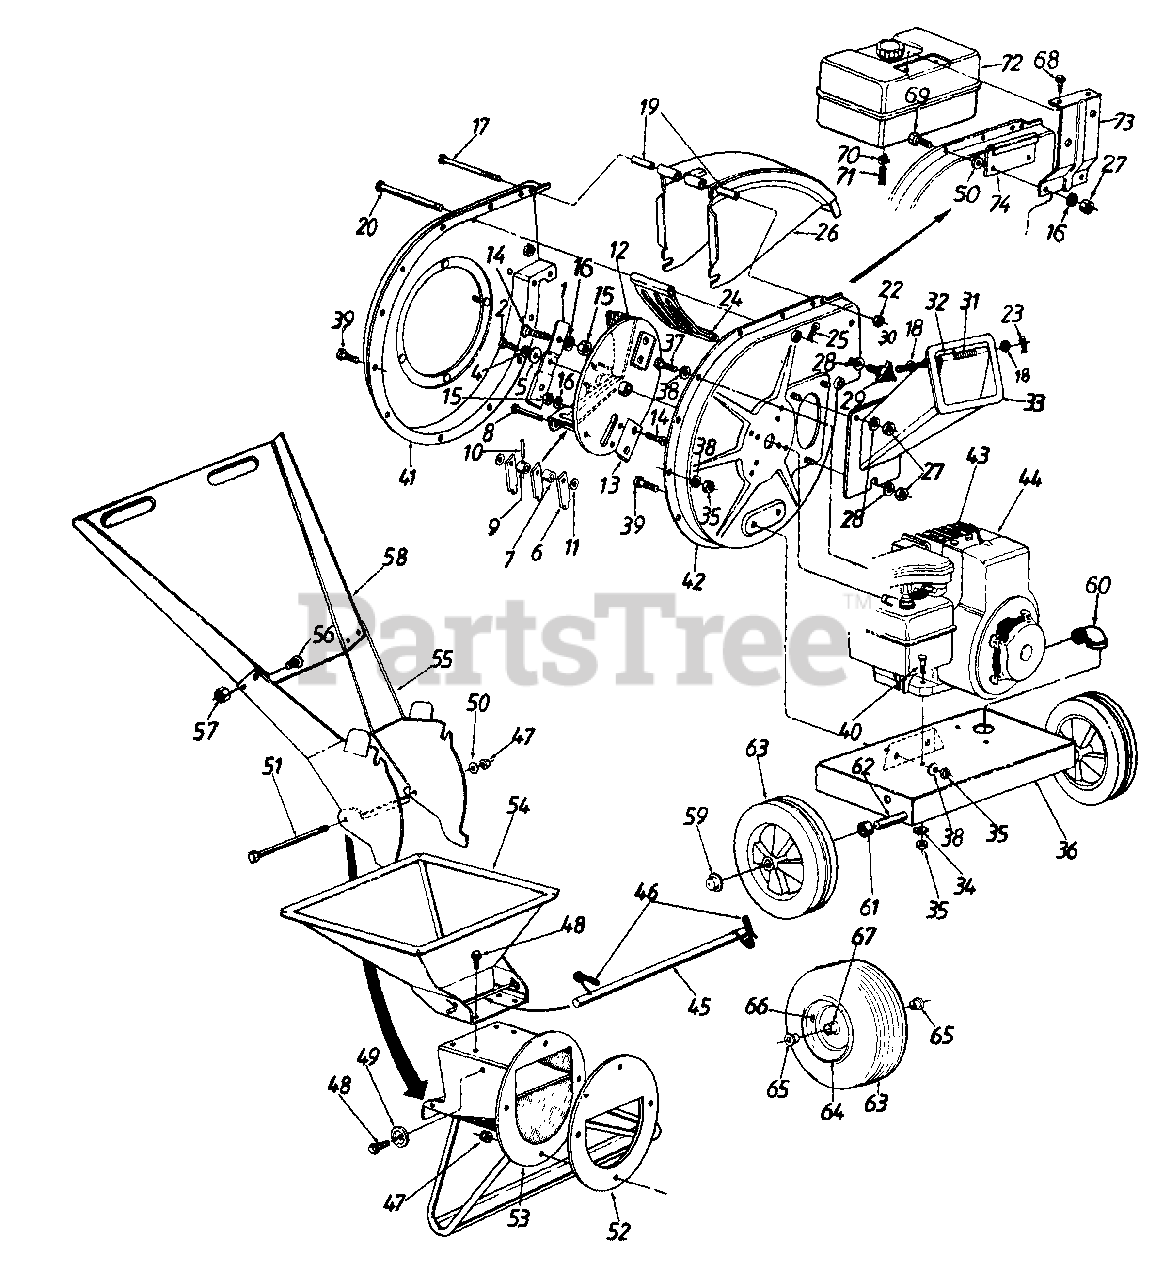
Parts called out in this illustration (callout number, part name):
1	Blade
2	Hex Patch Bolt 3/8-24 x 2.25" (Gr. 8)
4	L-Wash. 3/8" I.D. H.D.
5	Fl-Wash .406" I.D. x 1.25" O.D. Hdn.
6	Flail
7	Flail Spacer
8	Clevis Pin .496" Dia.
9	Flail Spacer w/.160" Dia. Hole
10	Spring Roll Pin 1.125" Lg.
11	Fl-Wash .531" I.D. x .94" O.D.
12	Impeller Ass'y. Comp.
13	Chipper Blade
14	Flat Hd. Scr. 5/16-24 x .75" Lg.
15	Hex Top L-Nut 5/16-24 (Gr. 5)
16	L-Wash. 5/16" I.D.
17	Hex Bolt 1/4-20 x 3.75" Lg.
18	Fl-Wash .281" I.D. x .5" O.D.
19	Chute Hinge Spacer 1.66" Lg.
20	Clevis Pin .5" Dia. x 4.62" Lg.
22	Hex Ctr. L-Nut 1/4-20 Thd.
23	Cotter Pin 3/32" x 5/8"
25	Internal Cotter Pin 3/8" Dia.
27	Hex Nut 5/16-18 Thd. (Gr. 5)
28	Bell-Wash .345" I.D. x .88"
29	Hand Knob
30	Chipper Door Rod
31	Torsion Spring 1.14" Lg.
35	Hex Nut 5/16-18 Thd. (Gr. 5)
38	L-Wash. 5/16" I.D.
39	Hex Bolt 5/16-18 x .75" Lg. (Gr. 5)
40	Hex Bolt 5/16-18 x 1.5" Lg.
44	Engine
45	Release Bar
46	Torsion Spring 1.06" Lg.
47	Elastic Lock Nut 5/16-18 Thd.
48	Hex Wash. Hd. Self-Tap Scr. 5/16-18 x .75" Lg.
49	Stop Washer
50	Fl-Wash. 5/16" I.D.
51	Hex Bolt 5/16-18 x 8.38" Lg.
57	Hex L-Nut 1/4-20 Thd.
60	Drain Elbow
61	Spacer.64" I.D. x .38" Lg.
62	Shredder Axle
63	Wheel Ass'y. Comp. (Plastic - 10 x 2.5)
64	Rim Only
65	Flange Bearing .632" I.D.
66	Air Valve
67	Grease Fltting
68	Hex Hi-Low Scr. 1/4 x .75"
69	Hex Bolt 5/16-18 x .88" Lg.
70	Hose Clamp
71	Fuel Line - 7 in.
72	Fuel Tank Ass'y. Comp.
